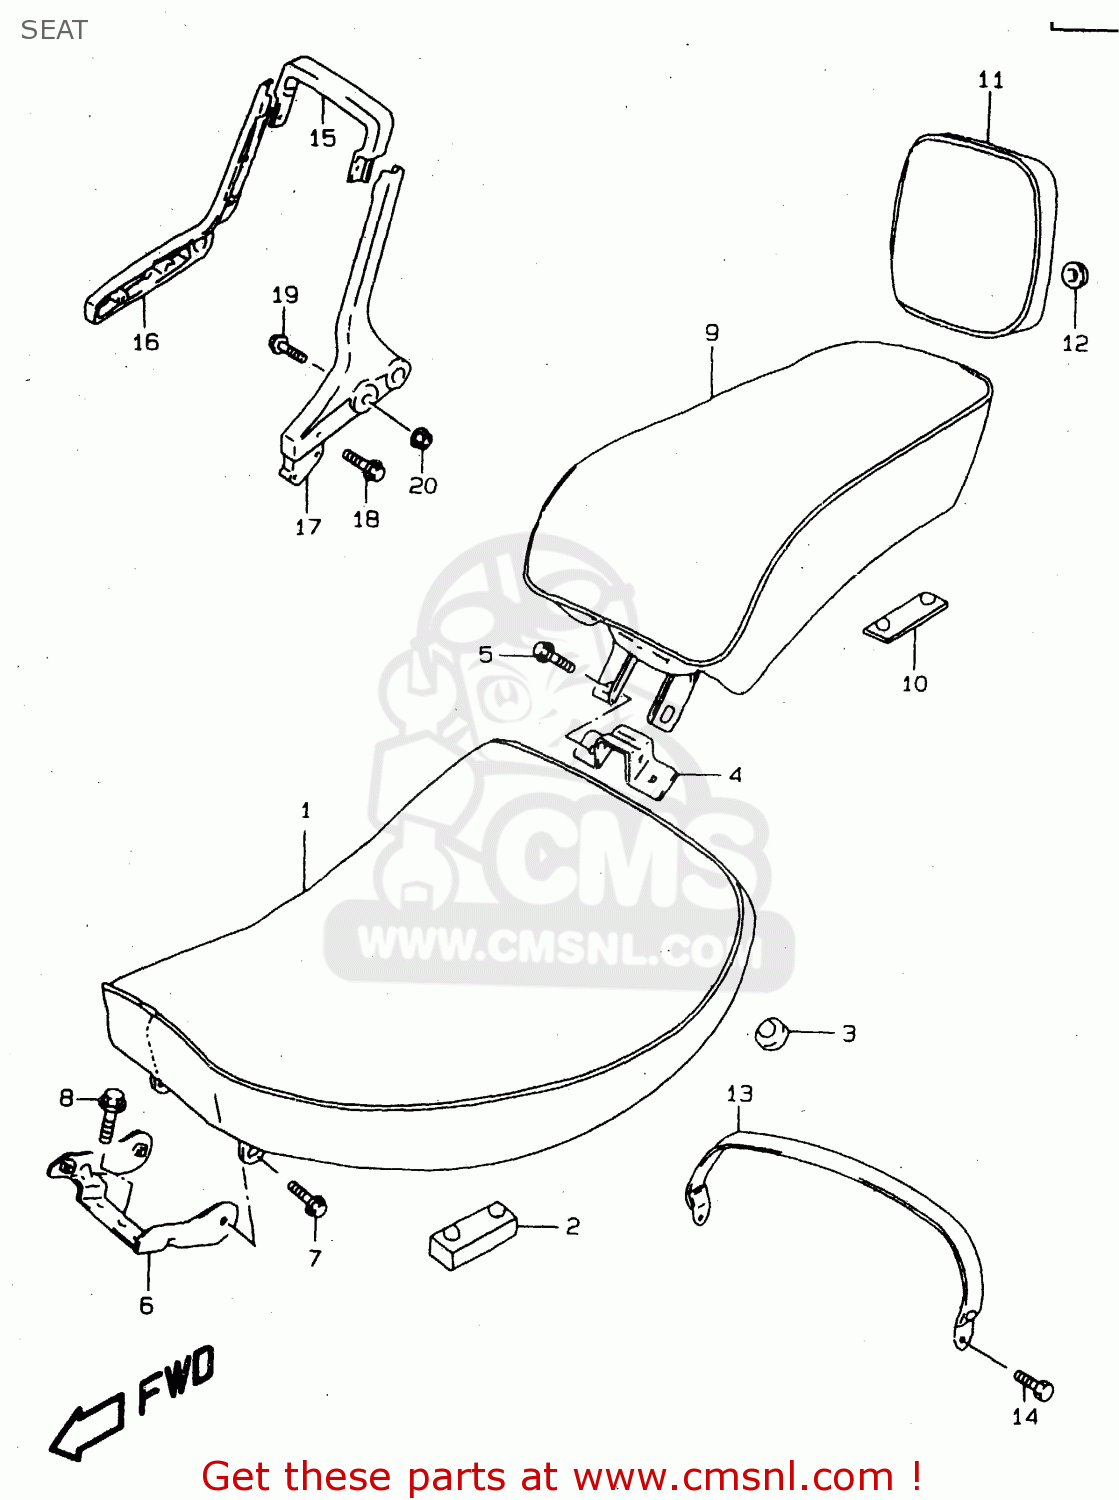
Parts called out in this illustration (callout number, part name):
1	SEAT ASSY
2	CUSHION,SEAT
3	CUSHION
4	PLATE,FR SEAT HOOK & RR
5	BOLT(6X16)
6	BRACKET,SEAT FR
7	BOLT(6X16)
8	BOLT
9	SEAT ASSY,PILLION
10	CUSHION
11	PAD ASSY,SEAT
12	CUSHION
13	BAND, SEAT
14	BOLT
15	HANDLE,PILLION RIDER UPR
16	HANDLE,PILLION RIDER,RIGHT
17	HANDLE,PILLION RIDER,L
18	BOLT
19	BOLT
20	NUT
